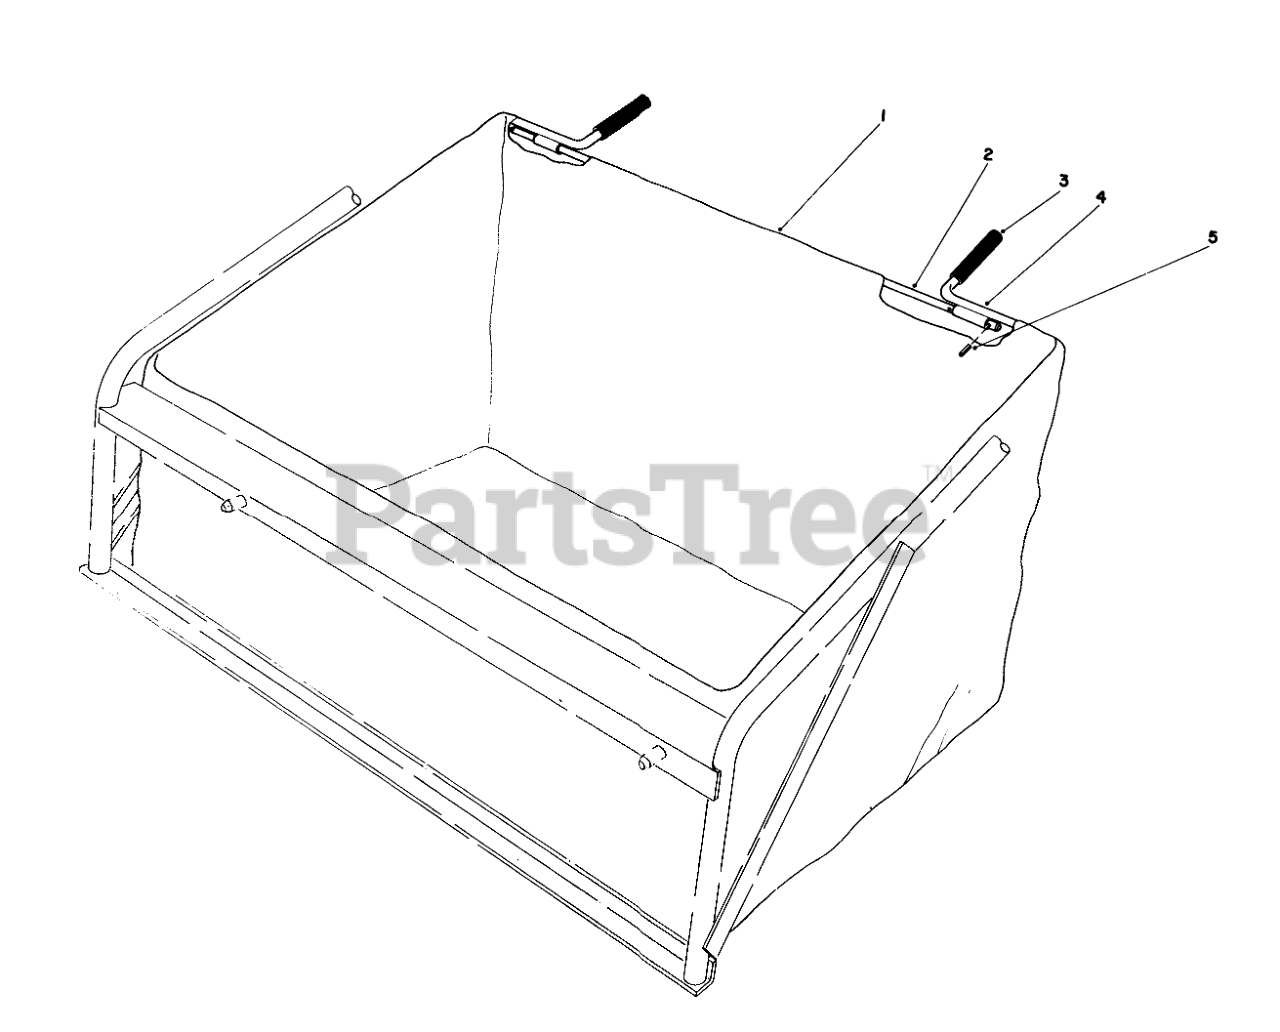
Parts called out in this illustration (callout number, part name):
1	Bag-Leaf Catcher
2	BAG FRAME ROD
3	BAG HANDLE GRIP
4	HYD HOSE ASM
5	PIN-ROLL
